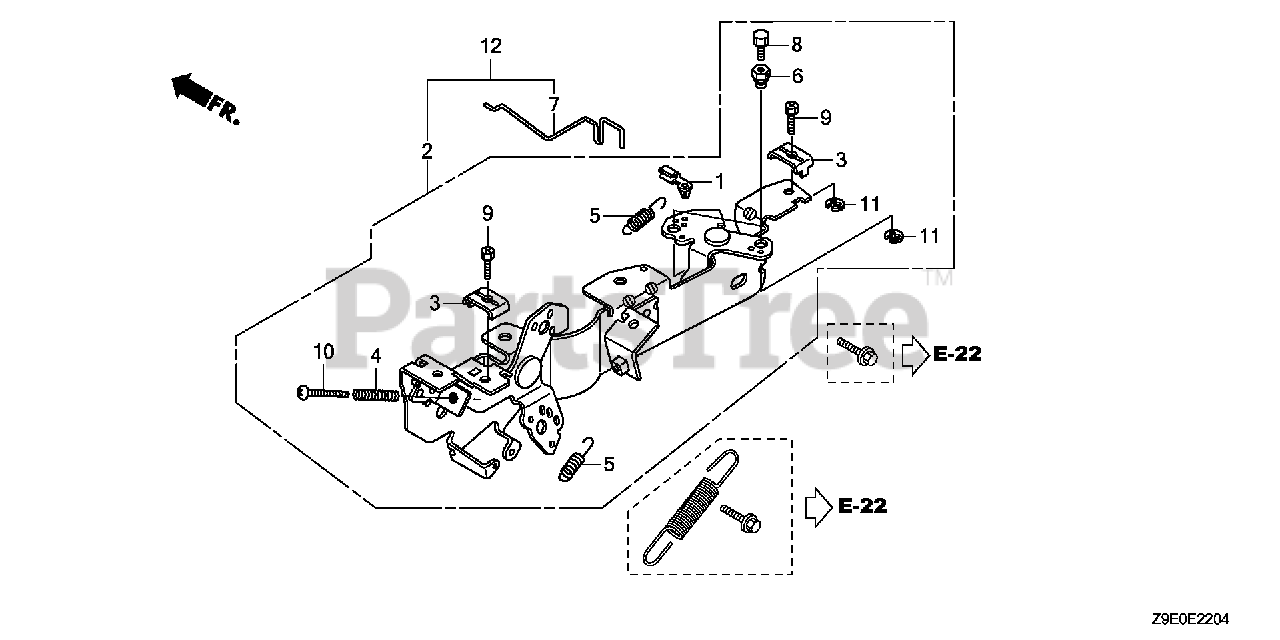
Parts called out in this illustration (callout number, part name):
1	JOINT, ROD
2	CONTROL ASSY.
3	HOLDER, CABLE
4	SPRING, CONTROL ADJUSTING
5	SPRING, CABLE RETURN
6	HOLDER, WIRE
7	ROD, CHOKE CONTROL
8	BOLT, RECESSED (4X6)
9	BOLT, RECESSED (5X16)
10	SCREW, PAN (5X40)
11	E-RING (5MM)
12	CONTROL KIT
